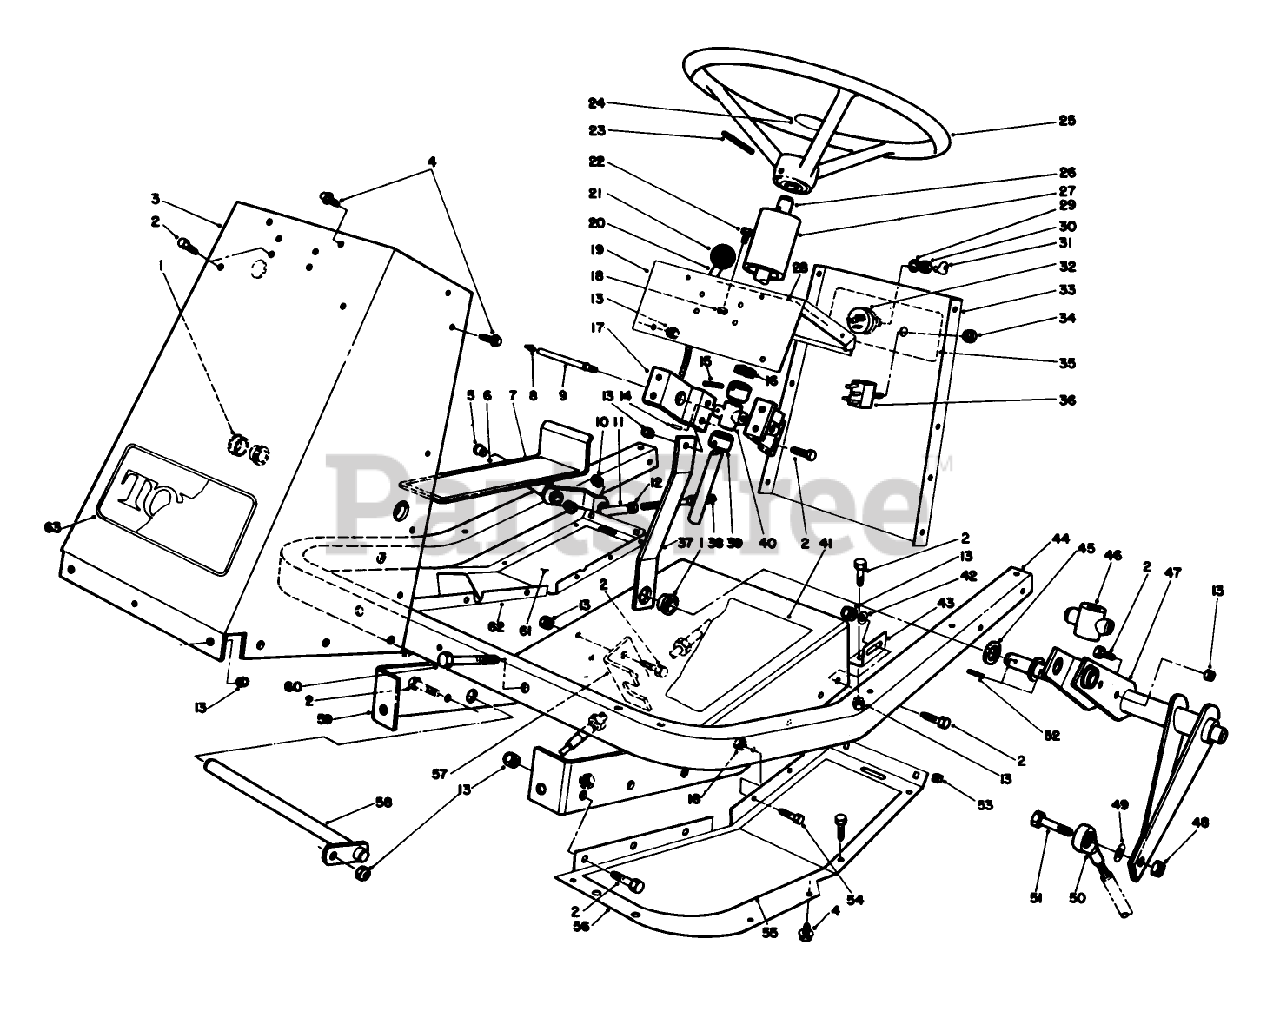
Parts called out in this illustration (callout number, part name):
1	BEARING-FLANGE
2	SCREW-HH
4	SCREW-HHFTF
5	BUSHING-FLANGE
8	FITTING-GREASE
9	TUBE ZERK
10	NUT-LOCK
11	JOINT-BALL
12	NUT-JAM
13	NUT-LOCK, NI
14	3/32 X 9/16 ROLL PIN
15	PIN-SPRING
16	COVER-DUST
17	BRG SUPT BRKT
18	NUT-LOCK, NI
20	CONTROL-CHOKE,THROTTLE
22	SCREW-HH
23	PIN-ROLL
24	STEERING WHEEL CAP
27	STRG. SHAFT COVER
28	THROTTLE DECAL
29	Washer-Lock
30	Nut-Hex
32	SWITCH
39	STRG SHAFT COLLAR
40	BRG STEERING SHAFT
42	WASHER-PLAIN
43	TUNNEL BRKT
45	WASHER-THRUST
46	STEER.SHAFT FOLLOWER
48	NUT-HEX
49	WASHER-FLAT
50	BALL JOINT LH
51	SCREW-HH
52	PIN-ROLL
53	NUT-RETAINED
54	SCREW-HH
58	PEDAL.SHAFT WA
60	SCREW-HH
61	FOOT REST PAD RH
63	DECAL
